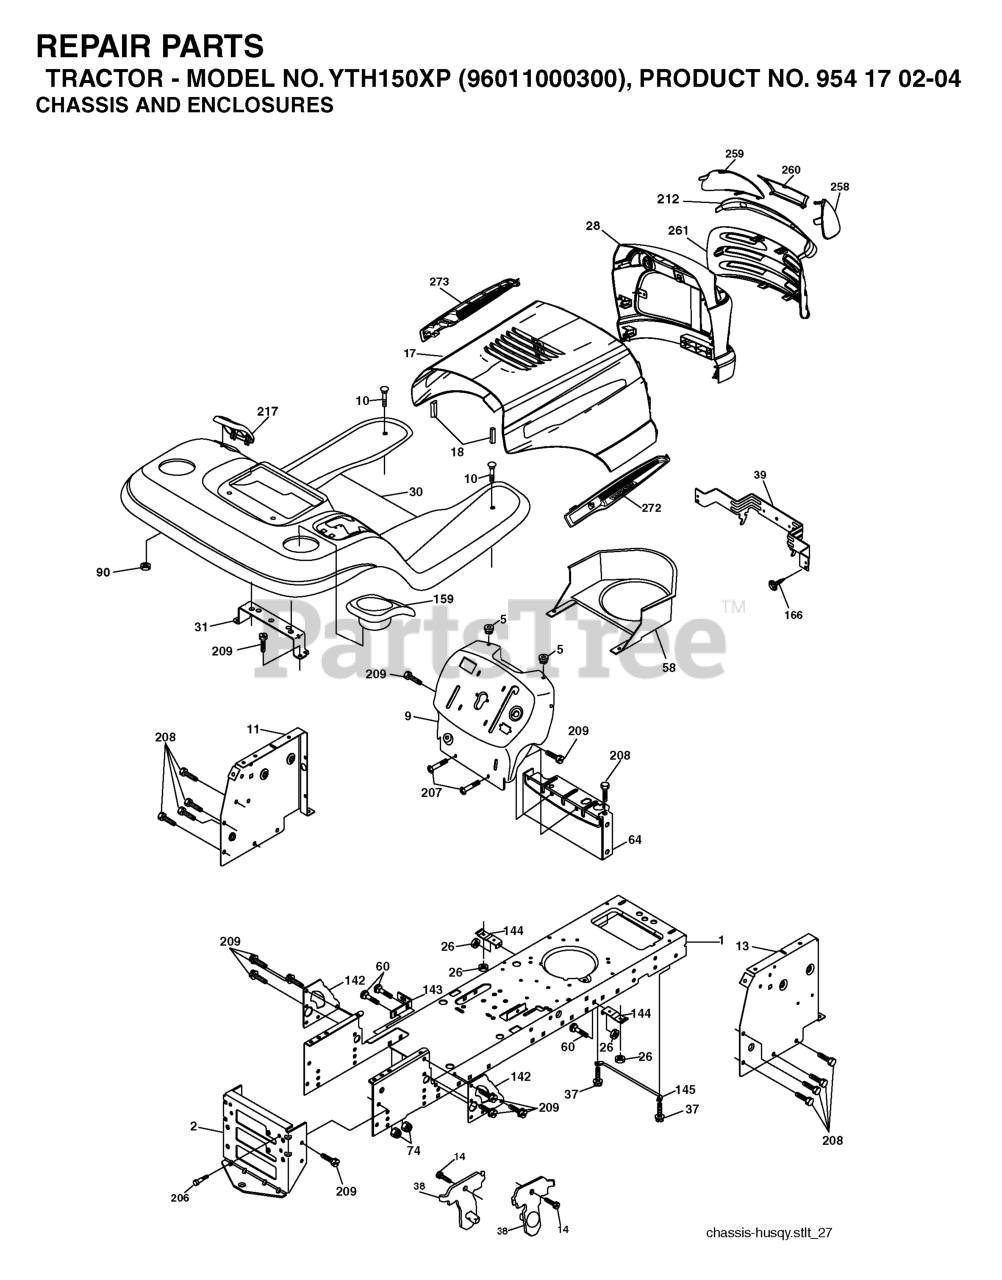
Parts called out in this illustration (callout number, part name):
1	CHASSIS STAMPING
2	DRAWBAR, 12GA
3	SCREW 3/8-16X3/4
5	BUMPER.RUBBER.HOOD
10	BOLT D
11	PANEL.DASH.LH.LTX
13	PANEL ASM, DASH RH
17	VENT.HOOD.LASER.III
18	BUMPER.HOOD.LARGE.1.75"
26	NUT
30	FENDER STL W/CUPHOLDER
31	BRACKET.SUPPORT.FENDER
37	Screw 5/16-18 x 1/2 Hex, Self Tapping 5/16-18 x 1/2
38	BRACKET.ASM.PIVOT.MOWER.REAR
39	BRACKET PIVOT LASER
60	Bolt - Rd. Hd. Sq. Neckiage 3/8 16 x 3/4
64	DASH LOWER
90	NUT.PUSH.3/16
142	PLATE REINFORCEMENT
143	BRACKET, SWAYBAR CHASSIS
144	BRKT, FOOT REST
145	ROD PIVOT CHASSIS/HOOD
159	GREY CUP HOLDER
166	SCREW
206	SHOULDER BOLT 5/16-18TT
207	SCREW, 5/16-18 X 1/2
208	SCREW 3/8-16X1/2
209	SCREW, 3/8-16X3/4
212	INSERT.LENS.REFLECTIVE
217	CONSOLE FUEL WINDOW
258	LENS LH
259	LENS LH
260	COVER.LENS.HUSQ.LASER
272	VENT.HOOD.LASER.
273	VENT.HOOD.LASER.
